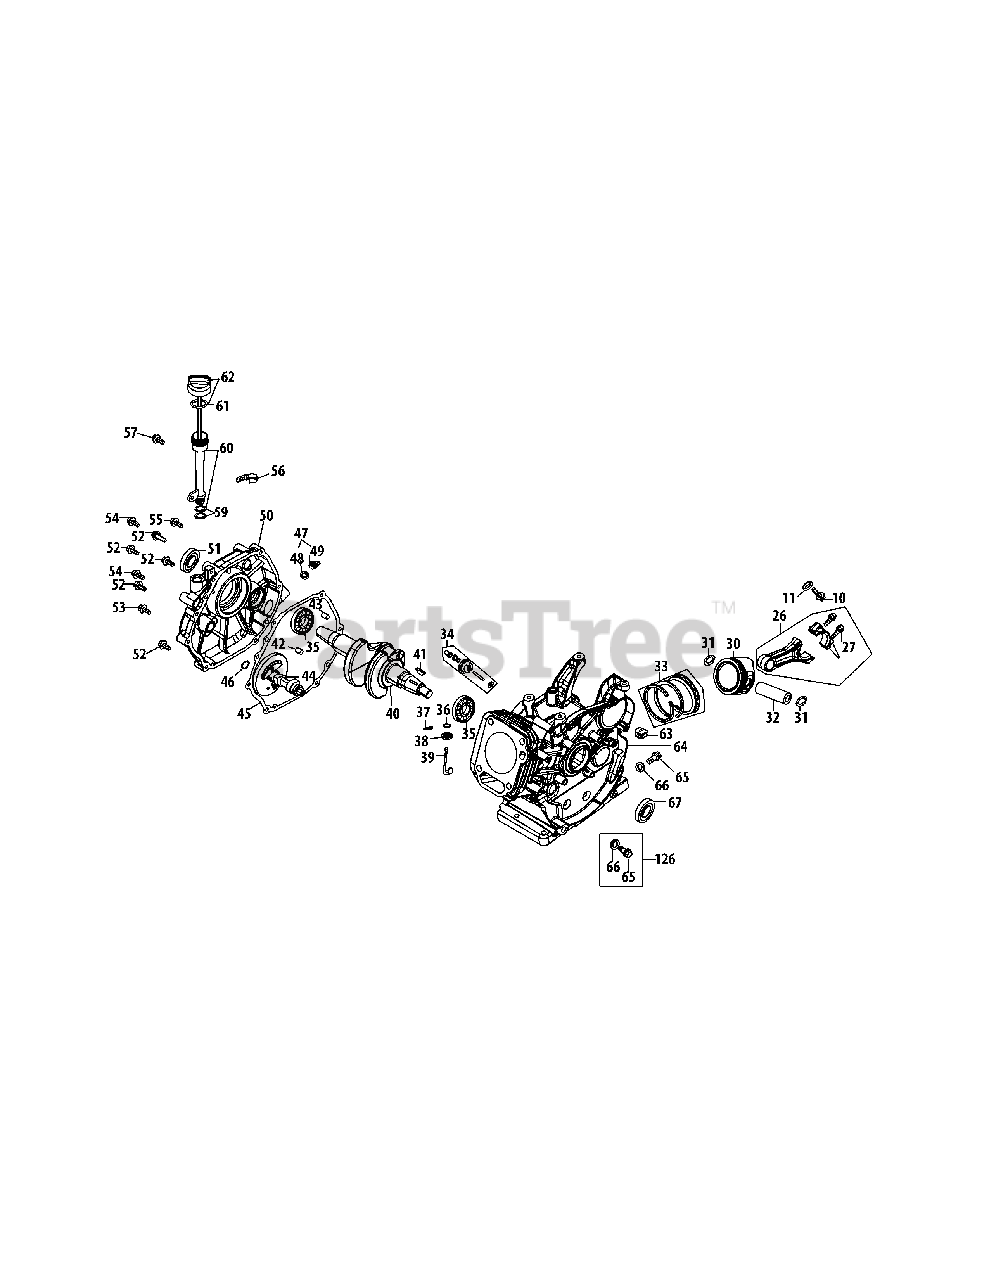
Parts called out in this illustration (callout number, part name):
10	Bolt M6×16
11	Washer, Flat
26	Connecting Rod Assembly
27	Connecting Rod Bolt
31	Piston Pin Snap Ring
32	Piston Pin
33	Piston Ring Kit
34	Governor Gear/Shaft Assembly
35	Radial Ball Bearing
36	Washer 8×20×0.8
37	Cotter Pin
38	Governor Seal
39	Governor Arm Shaft
40	Crankshaft Assembly
41	Woodruff Key
42	Dowel Pin 9×12
43	Dowel Pin 7×14
44	Camshaft Assy.
45	Crankcase Cover Gasket
46	Washer 16×24×0.5
47	Oil Filler Plug Assembly
48	O-Ring 15.8×2.5
49	Oil Filler Plug
50	Cover Comp,Left Crankcase
51	Oil Seal,30×46×8
52	Bolt M8×38
53	Bolt M8×45
54	Bolt M8×35
55	Bolt M6×16
56	Dipstick Clamp
57	Bolt M6×8
59	Oil Fill Tube O-Ring
60	Oil Fill Tube Asm (Incl 59)
61	Dipstick O-Ring
62	Dipstick Assembly (Incl 61)
63	Wire Clamp Rubber
64	Short Block
65	Oil Drain Plug
66	Washer 12×20×2
67	Oil Seal 30×46×8
126	Oil Drain Plug & Washer Assembly
